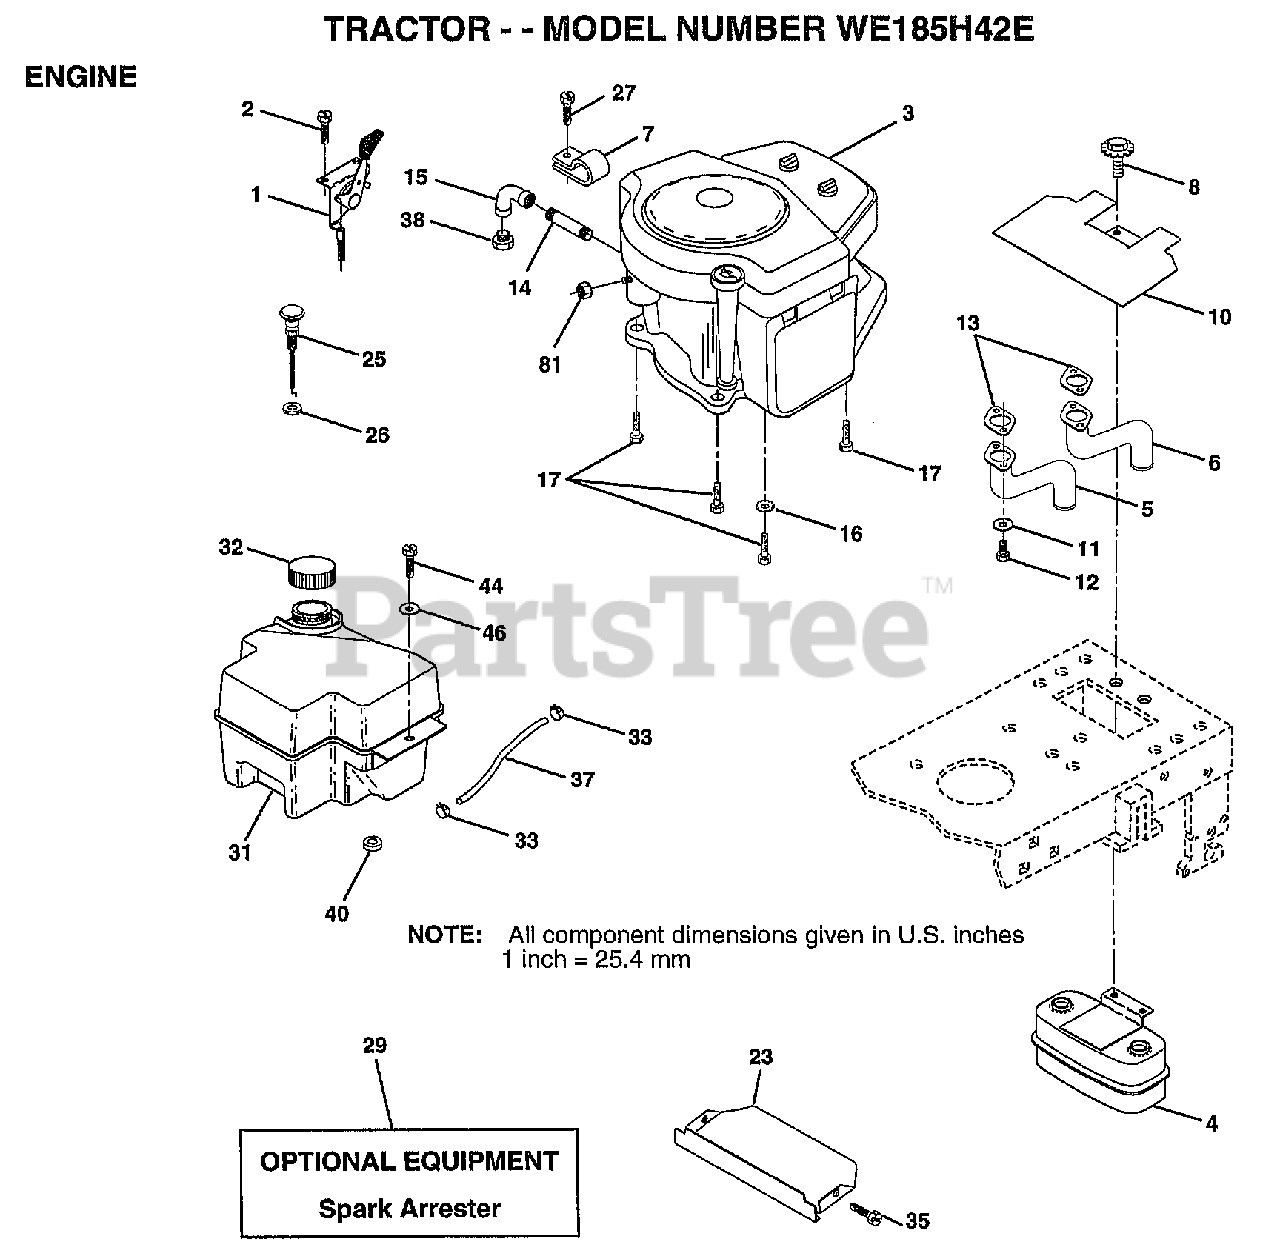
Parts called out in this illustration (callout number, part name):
1	CONTROL THRT 35.5
2	SCREW LT
4	MUFFLER.TW.LOTONE
5	EXHAUST.B&S.18.LH
6	EXHAUST.B&S.18.RH
7	CLAMP.TUBE.DBL.EN
8	BOLT.5/16-18.UNC
10	SHIELD.HEAT.
11	LOCKWASHER
13	GASKET MUFFLER
14	PIPE NIPPLE LT
15	ELBOW
16	LOCKWASHER
17	SCREW LT
23	SHIELD.BRN/DBR.GD
25	CONTROL.CHOKE.37
26	"NUT,KEPS 3/8-24IM"
27	"SCREW-TT,10-32 FL"
31	TANK.FUEL.FRONT.
32	CAP ASM FUEL
33	HOSE CLAMP
35	SCREW
37	LINE FUEL
44	SCREW HEX CRT
46	WASHER
81	NUT
